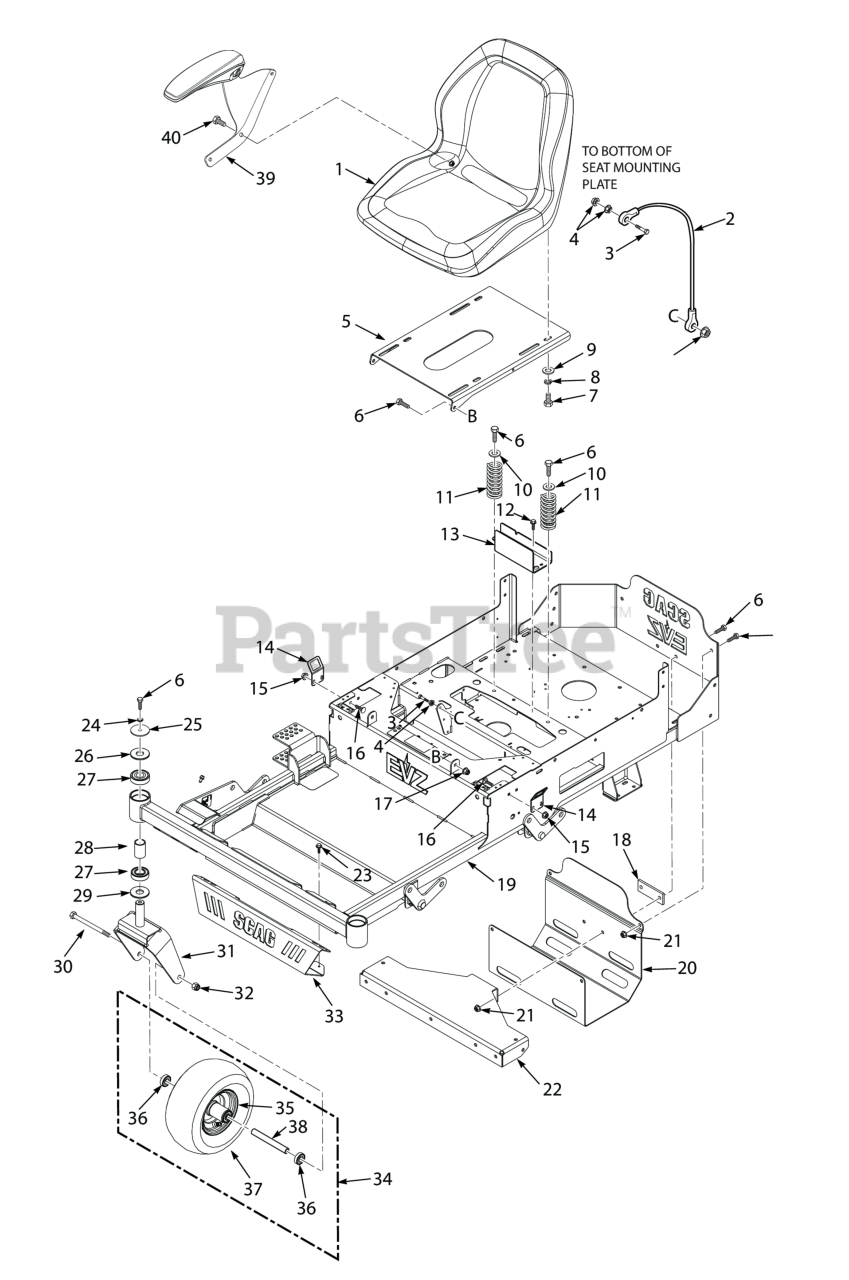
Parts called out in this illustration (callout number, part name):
1	Seat, SZL w/Armrests
2	Cable, Seat Stop
3	SERR. FLG. HEX HEAD CAPSCREW, 5/16-18 X 3/4
4	NUT, 1/4-20 SERRATED FLANGE HEX HEAD
5	Seat-Plate W/Decal
6	Bolt, Hex Head, 3/8-16 x 1 Gr. 5
7	Bolt, Heax Head 5/16-18 x 1" (48V / 52V)
8	Lockwasher, 5/16 (.317 x .586 x .078) Helical Spring
9	Flatwasher, 5/16-.375 x .875 x .083 (35BV & 37BV-EFI)
10	Flatwasher, 3/8" Special (.391 x .938 x .105)
11	Spring, Seat
12	Capscrew, 5/16-18 x .75 Serrated Flange Hex Head
13	Channel, Hose
14	Bracket, Switch
15	Nut, Flanged Elastic Stop 1/4-20
16	Serr. Fl. Hex Head CPSCR, 1/4-20 x 3/4"
17	Nut, Flange Elastic Stop Nut, 3/8-16
18	Plate, Spacer
19	Mainframe w/Decals
20	Skid Plate, SZL
21	NUT, 3/8-16 SERRATED FLANGE HEX HEAD
22	Support, Battery
23	Screw, 1/4-20 x .375"
24	Lockwasher, 3/8" Spring, Kawasaki FX / FT & FT-EFI / B&S 32BV
25	Flatwasher, 3/8-.406 x 2.25" x .1875
26	Flatwasher, 7/16" (.500 x 1.25 x .083")
27	Bearing
28	Spacer, Caster Bearing
29	Spacer, Yoke
30	Bolt, Hex Head 1/2-13 x 7-1/2" (48"/52")
31	Caster Yoke Assembly (incl. 30, 32, & 34)
32	HEX LOCKNUT, ELASTIC STOP, 1/2-13
33	Bumper. Front
34	CASTER WHEEL ASSY, 11.00 X 6.00-5
35	RIM ASSY, 5 X 3 W/5.625 LG HUB
36	Bearing
37	TIRE, 11 X 6.00-5
38	SPACER, WHEEL BEARING
39	Armrest, RH (48H, 52H, 61H)
40	SCR,HHSCR, 1/4-14 X1 TYPA THRD FRMNG
